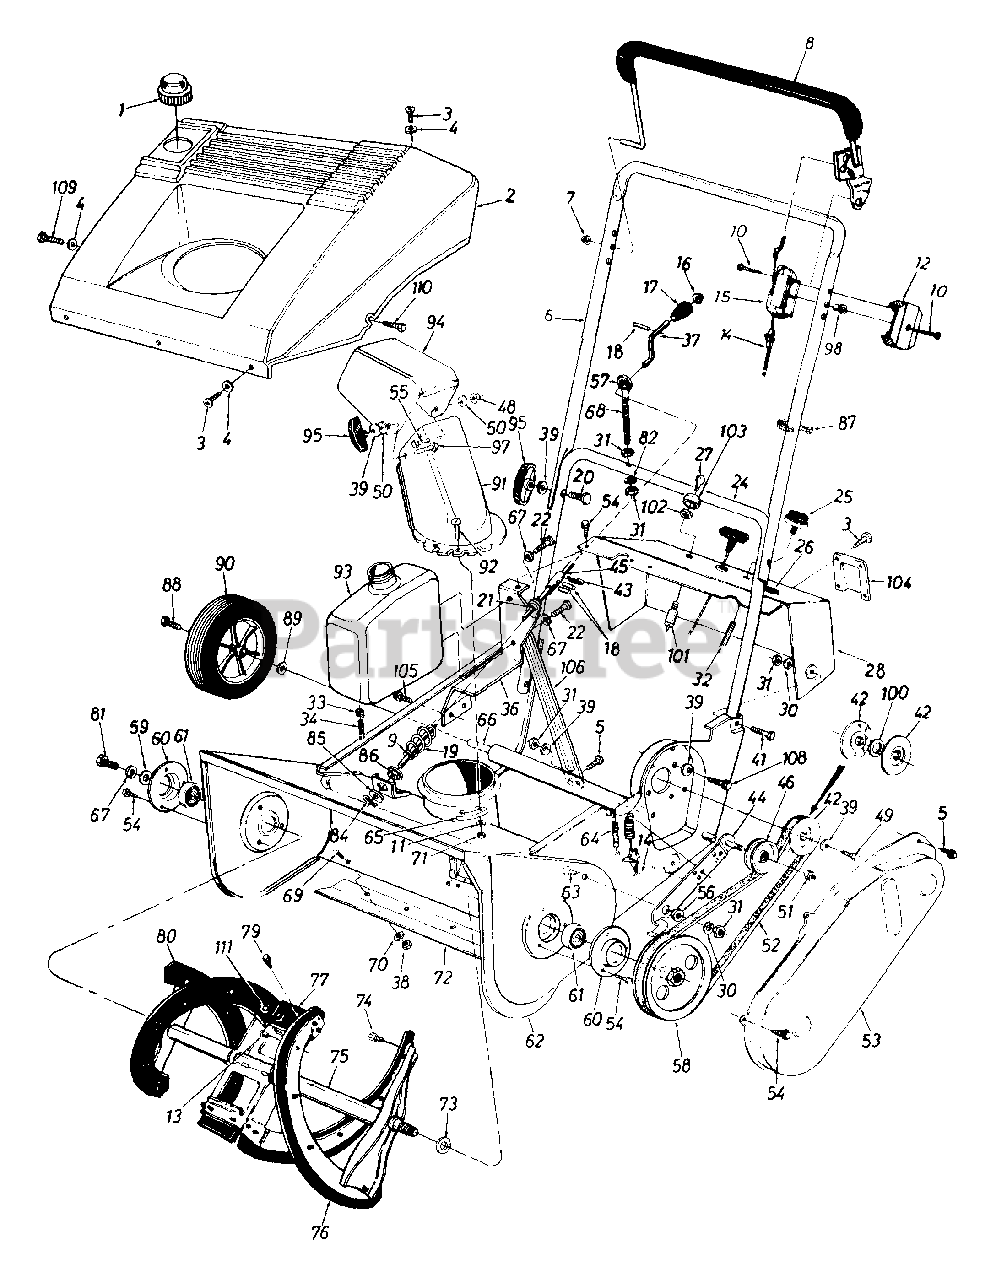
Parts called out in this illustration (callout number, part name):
1	Gas Tank Cap
2	Shroud
3	Hex B-Tap Scr. #10 x .5" Lg.
4	Fl-Wash. .203" I.D. x.41"
5	Hex L-Wash. Hd. AB-Tap 1/4 x .62" Lg.
8	Control Handle Ass'y.- L.H.
9	Fl-Wash. .385" I.D. x .62"
10	Truss Mach. Hi-B Tap Scr. #12 x 1.5" Lg.
11	Fl-Wash. .281" I.D. x .5" O.D.
12	Control Panel Half
13	Pop Rivet .187" Dia.
14	Clutch Cable 35" Lg.
15	Control Panel Half
16	Push Cap 3/8" Rod
17	Knob - 3/8" Dia. Hole
18	Roll Pin 1/8" Dia. x .63" Lg.
19	Lower Chute Crank Ass'y.
20	Curved Carriage Bolt 5/16-18 x 1.75" Lg.
21	Chute Crank Grommet
22	Hex Bolt 1/4-20 x .5" Lg.
26	Plastic Plug
31	Hex Nut 5/16-18 Thd.
32	Primer Hose - 9" Lg.
33	Hose Clamp - 1/2" O.D.
34	Gas Line 26" Lg.
36	Gas Tank Support Brkt.
38	Hex Jam Nut 1/4-20 Thd.
39	Bell-Wash. .345" I.D. x .88"
41	Hex Bolt 5/16-18 x 1.5" Lg.
42	3/8" "V"-Pulley Half .625" I.D. x 6.0" O.D.
43	Cotter Pin 3/32" Dia.
46	Fl-Idler w/Flanges 2.12" O.D.
48	Hex L-Nut 5/16-18 Thd.
49	Hex Bolt 5/16-24 x .75" Lg.
50	Fl-Wash. .344" I.D. x 1.25"
51	Hex Patch L-Nut 3/8-24 Thd.
52	"V"-Belt
54	Hex B-Tap Scr. 1/4" x .38" Lg.
55	Carriage Bolt 5/16-18 x .75"
56	Shld. Spacer .50" Dia. x .27"
57	Plastic Bushing .38" I.D.
58	1/2" "V"-Pulley 1/2-20 L.H. x 6"
59	Fl-Wash. 1/4" I.D. x .93" O.D.
64	Extension Spring 1.12" Lg.
65	Chute Flange Keeper
66	Wheel Axle 20.6" Lg.
67	L-Wash. 1/4" I.D.
68	Eyebolt
69	Carriage Bolt 1/4-20 x .50"
70	Fl-Wash. .281" I.D. x .73"
71	Hex L-Nut 1/4-20 Thd.
72	Shave Plate
73	Fl-Wash. .510" I.D. x 1.0" O.D.
74	Hex Wash. B-Tap Scr. 1/4 x .62" (Spec.)
76	Rubber Spiral - L.H.
77	Rubber Paddle
79	Hex Wash. B-Tap Scr. #10 x .62" Lg.
80	Rubber Spiral - R.H.
81	Hex Wash. TT-Tap CI-Scr. 1/4-20 x .75" Lg.
82	Saddle Wash. .32" I.D.
84	Cotter Pin 3/32" Dia. x .75"
85	Fl-Wash. .406" I.D. x 1.25"
86	Hex Bushing .385" I.D.
87	Cable Tie
88	Hex Tap Scr. 3/8-24 x .5" Lg.
89	Fl-Wash. .510" I.D. x .75"
90	7" Wheel & Tire Ass'y.
91	Lower Chute
92	Truss Mach. Scr. 1/4-20 x .75"
93	Fuel Tank - Two Qt.
94	Upper Chute
95	Knob Handle Ass'y.
97	Carriage Bolt 5/16-18 x 1"
98	Control Disc Pin
100	Fl-Wash. .635" I.D. x .93" O.D.
101	Key Switch
102	Ignition Switch Nut 5/8-32 Thd.
103	Ignition Switch Cap
104	Choke Cover
105	Hex Wash. Hd. Tap Scr. 1/4-.5" Lg.
109	Pan Hd. Tap Scr. #10 x 1.25" Lg.
110	Hex Wash. Hd. Tap Scr. 1/4-20 x 1" Lg.
111	Torx AB-Tap Scr. 1/4 x .62" Lg.
